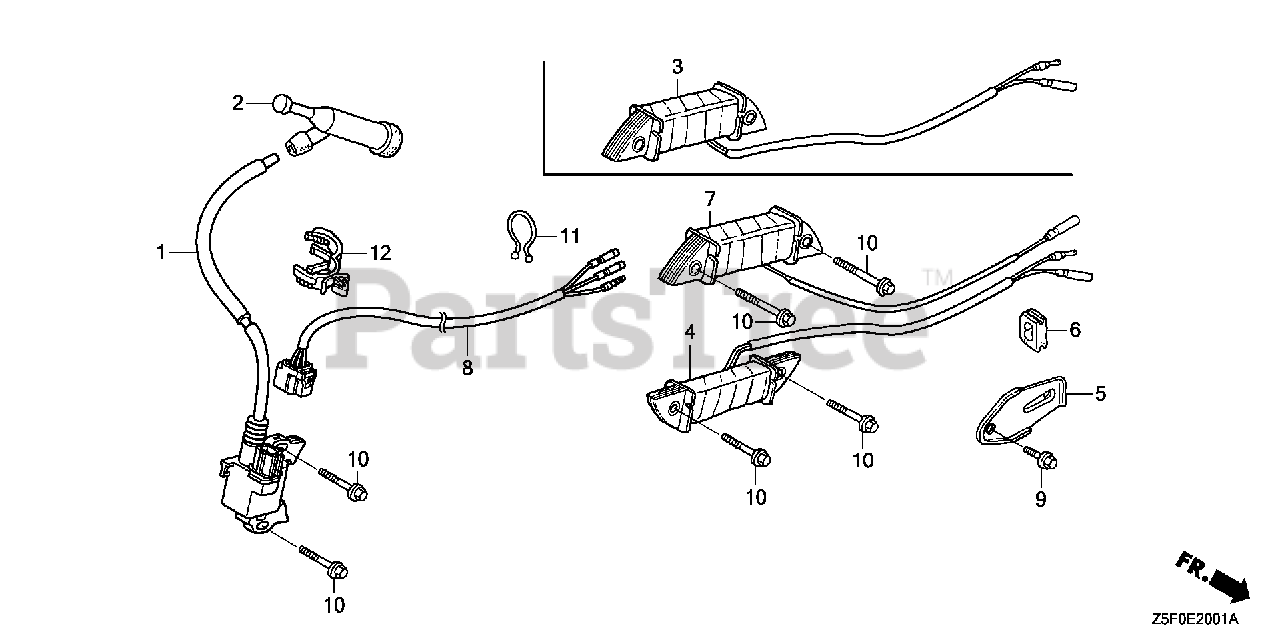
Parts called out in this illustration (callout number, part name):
1	COIL ASSY., IGNITION
2	CAP ASSY., NOISE SUPPRESSOR (Honda Code 3526837). (NICHIWA Y-EZ RTFM256)
6	GROMMET, WIRE
8	WIRE HARNESS ASSY., ENGINE
10	BOLT, FLANGE (6X28) (CT200) Use up to Engine SN 1530314.
12	CLIP, WIRE HARNESS
